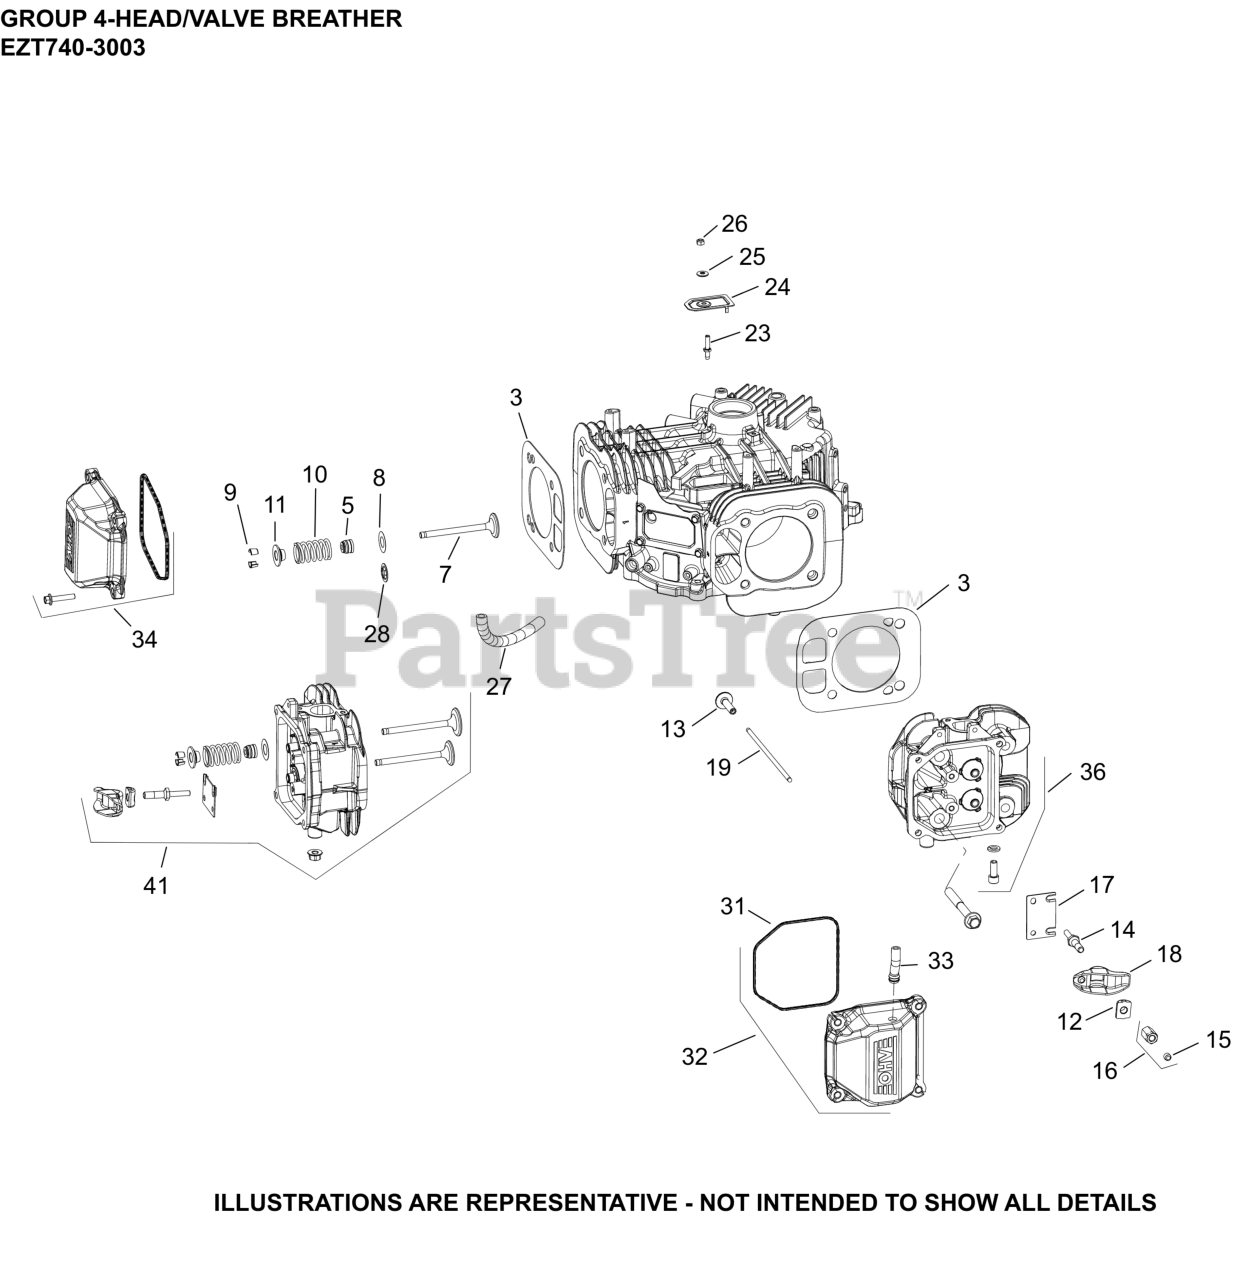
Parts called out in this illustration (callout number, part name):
3	KIT, GASKET CYLINDER HEAD
5	SEAL, VALVE BAND
7	VALVE, EXHAUST
7	VALVE, EXHAUST (.25)
8	SPACER (.010")
9	KIT, RETAINER
10	SPRING VALVE
11	CAP, VALVE SPRING
12	PIVOT, ROCKER ARM
14	STUD, ROCKER
15	SCREW, SET
16	HEX NUT ASSEMBLY
17	PLATE, GUIDE
18	ARM, ROCKER
19	ROD, PUSH
24	COVER, BREATHER REED
25	WASHER, SEALING
26	NUT, LOCK M5X.8
27	HOSE, BREATHER
28	RETAINER, VALVE GUIDE (KM)
31	O-RING (YELLOW), VALVE CO
32	KIT,BREATHER VALVE COVER (PLASTIC)
33	HOSE, FP-USE 32 326 07-S(PLASTIC COVERS)
34	KIT, VALVE COVER-PLAIN (PLASTIC)
36	KIT, HEAD #2 AND HARDWARE-(#1675521S)
41	KIT, CYLINDER HEAD #1
NI	VALVE, INTAKE (STD)
NI	VALVE, INTAKE (.25)-(#DSC)
NI	SCREW, HEX FLANGE M10 X 1.5-6g X 90mm
NI	SCREW, HEX FLANGE (M6 X 31.625 DOG PT)
